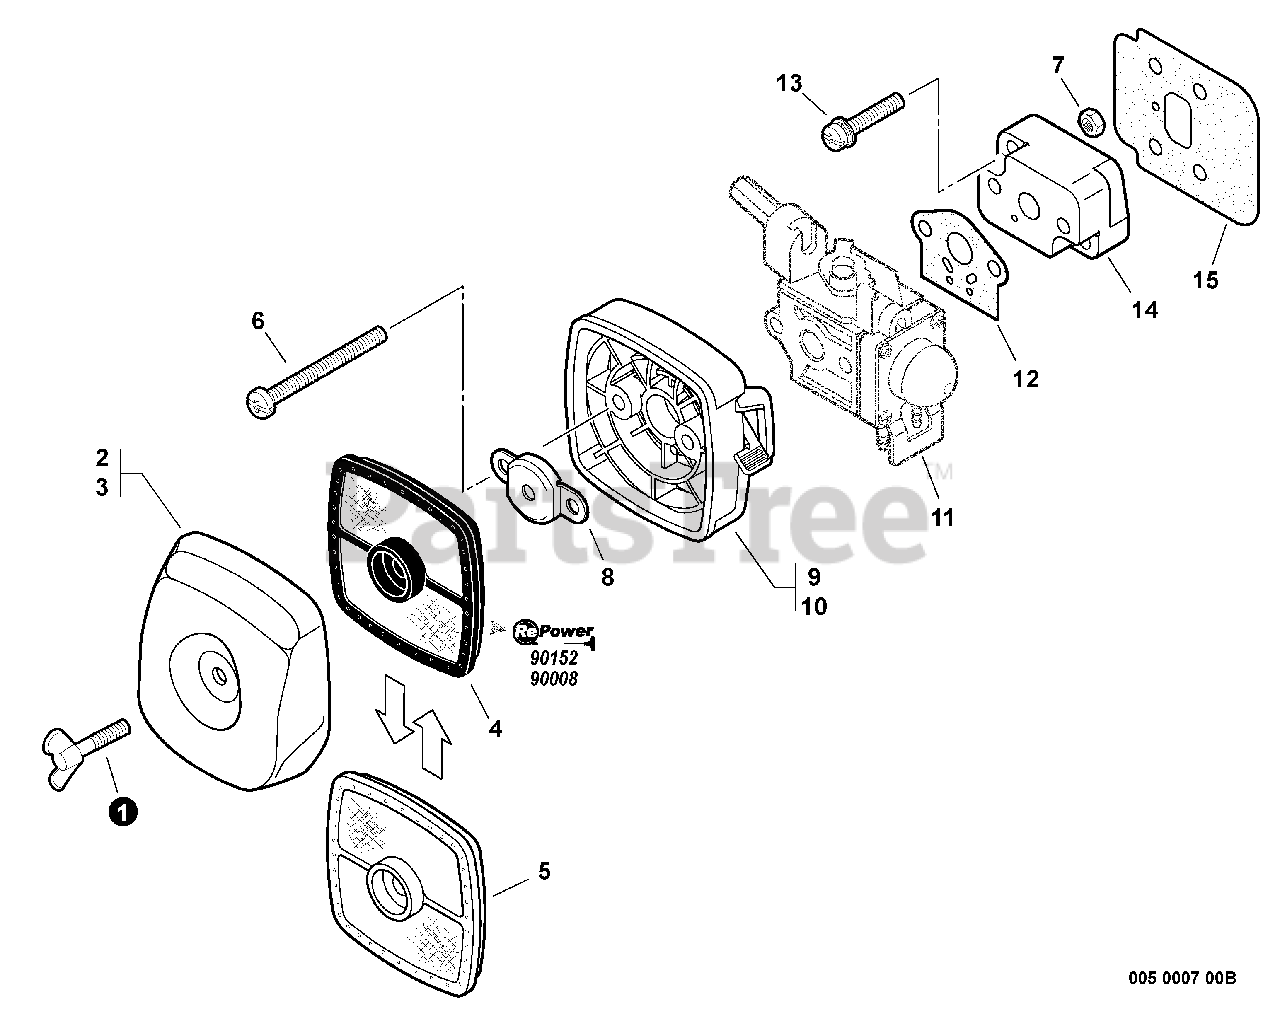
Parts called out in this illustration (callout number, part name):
1	BOLT, WING 5×20
2	COVER, AIR FILTER - GRAY
3	COVER, AIR FILTER - BLACK
4	FILTER, AIR - DOUBLE LAYER
5	FILTER, AIR - SINGLE LAYER
6	SCREW 5×65
7	NUT M5
8	PLATE, PREVENT
9	CASE, AIR FILTER - GRAY
10	CASE, AIR FILTER - BLACK
11	CARBURETOR
12	GASKET, CARBURETOR
13	SCREW 5×22
14	INSULATOR, INTAKE
15	HEAT SHIELD, INTAKE
16	FILTER KIT - REPOWER
17	TUNE-UP KIT - REPOWER
